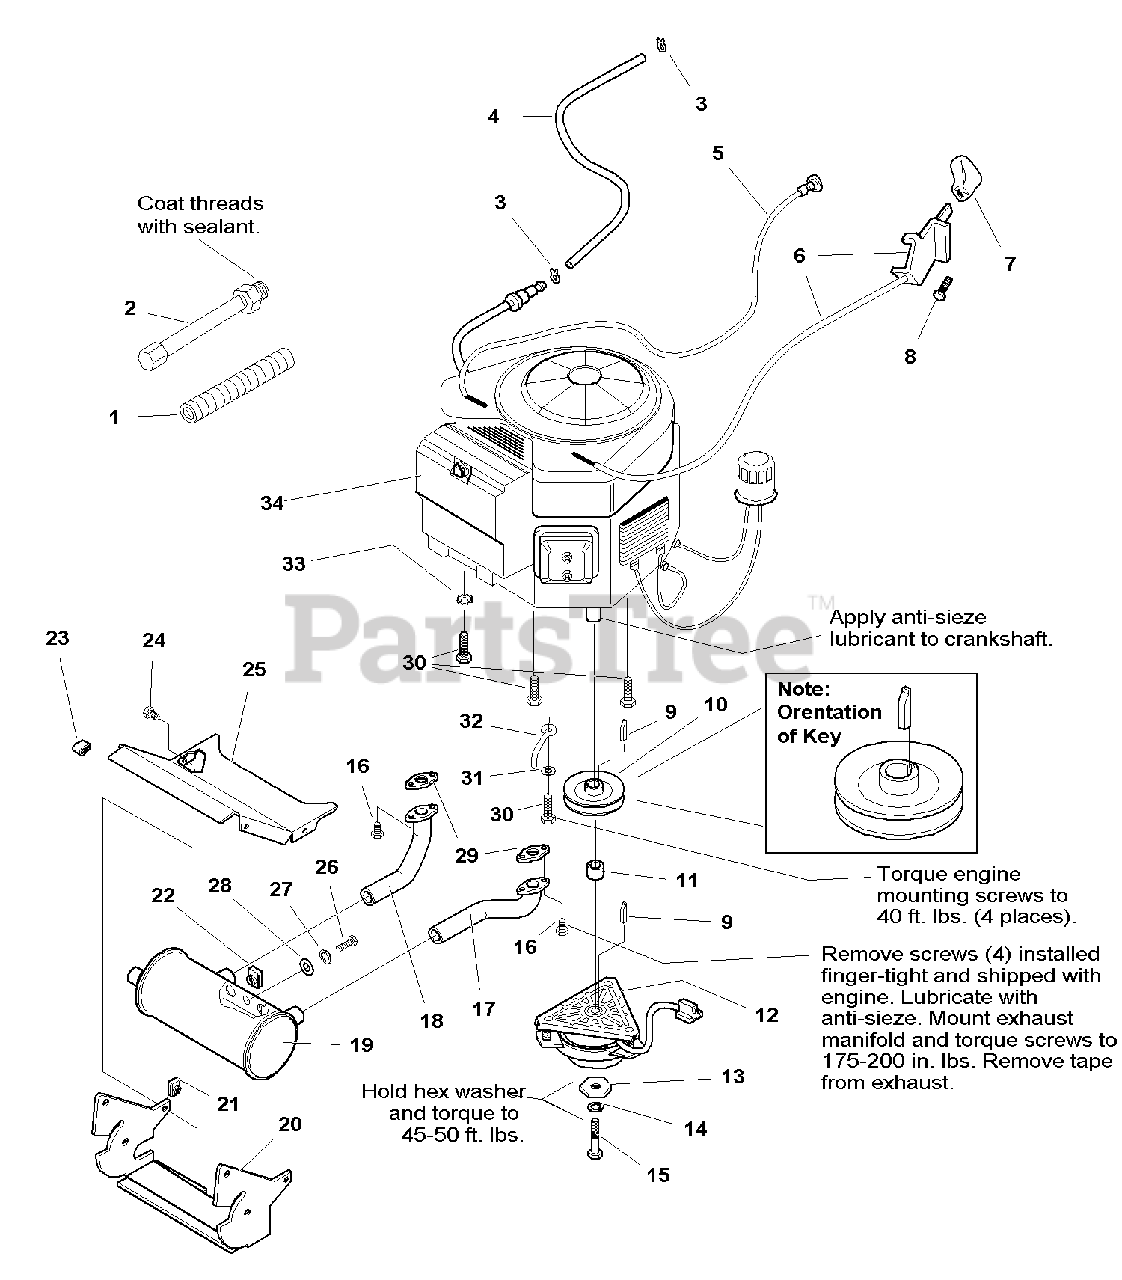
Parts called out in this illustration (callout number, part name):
1	TUBE, Flexible
2	HOSE, Oil Drain
3	CLAMP, Hose
4	HOSE, Fuel, 45-1/2
5	CABLE, Choke Control
6	THROTTLE CONTROL ASSEMBLY
7	KNOB, Throttle
8	CAPSCREW, Hex Head, Plastite, 1/4-20 x 1/2
9	KEY, Hi-Pro
10	PULLEY ASSEMBLY
12	ELECTRIC CLUTCH ASSEMBLY, PTO
13	WASHER, Hex
14	WASHER, Lock, 7/16
15	CAPSCREW, Hex Head, 7/16-20 x 4
16	CAPSCREW, Hex Head, 5/16-18 x 1
17	MANIFOLD PIPE, LH
18	MANIFOLD PIPE, RH
20	DUCT, Lower Exhaust
21	PAL NUT, 1/4-20
22	NUT, Speed, 5/16-18
23	CLIP
24	CAPSCREW, Hex Head, Whiz Lock, 1/4-20 x 5/8
25	DUCT, Upper Exhaust
26	CAPSCREW, Hex Head, M8-1,25 x 20mm
27	WASHER, Lock, 5/16
28	WASHER, 5/16
29	GASKET
30	CAPSCREW, Hex Head, Taptite, 3/8-16 x 1-1/2
31	WASHER, 3/8
33	WASHER, Lock, External Tooth
34	Engine, 23HP Kohler V-Twin
